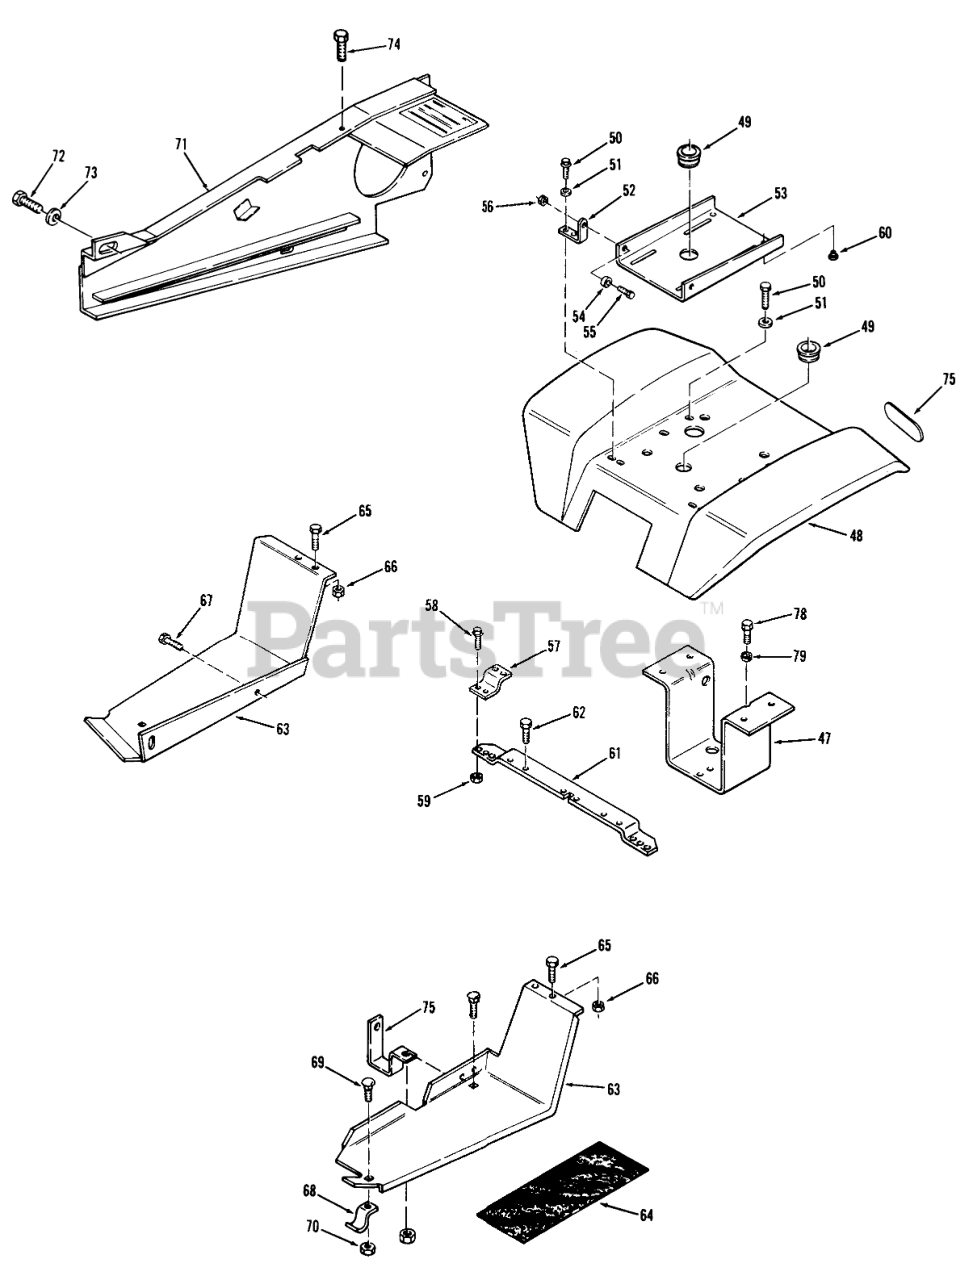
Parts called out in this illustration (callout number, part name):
47	Bracket-Fender
48	Fender
49	Bushing
50	Bolt
51	WASHER 5/16 SAE
52	BRACKET-PIVOT
53	Plate Seat Pivot
54	BUSHING
55	HHCS
56	Nut
57	BRACKET-FENDER R
58	HHCS
59	Nut
60	BUMPER-RUBBER
61	Bracket-Footrest
62	SCREW
63	Footrest-LH
63	Footrest-RH
64	PAD-FOOTREST
65	Bolt
66	Nut
67	Screw
68	BRACKET
69	Bolt
70	Nut
71	Belt Guard
72	H H C S
73	LOCKWASHER
74	Screw
75	Bracket
